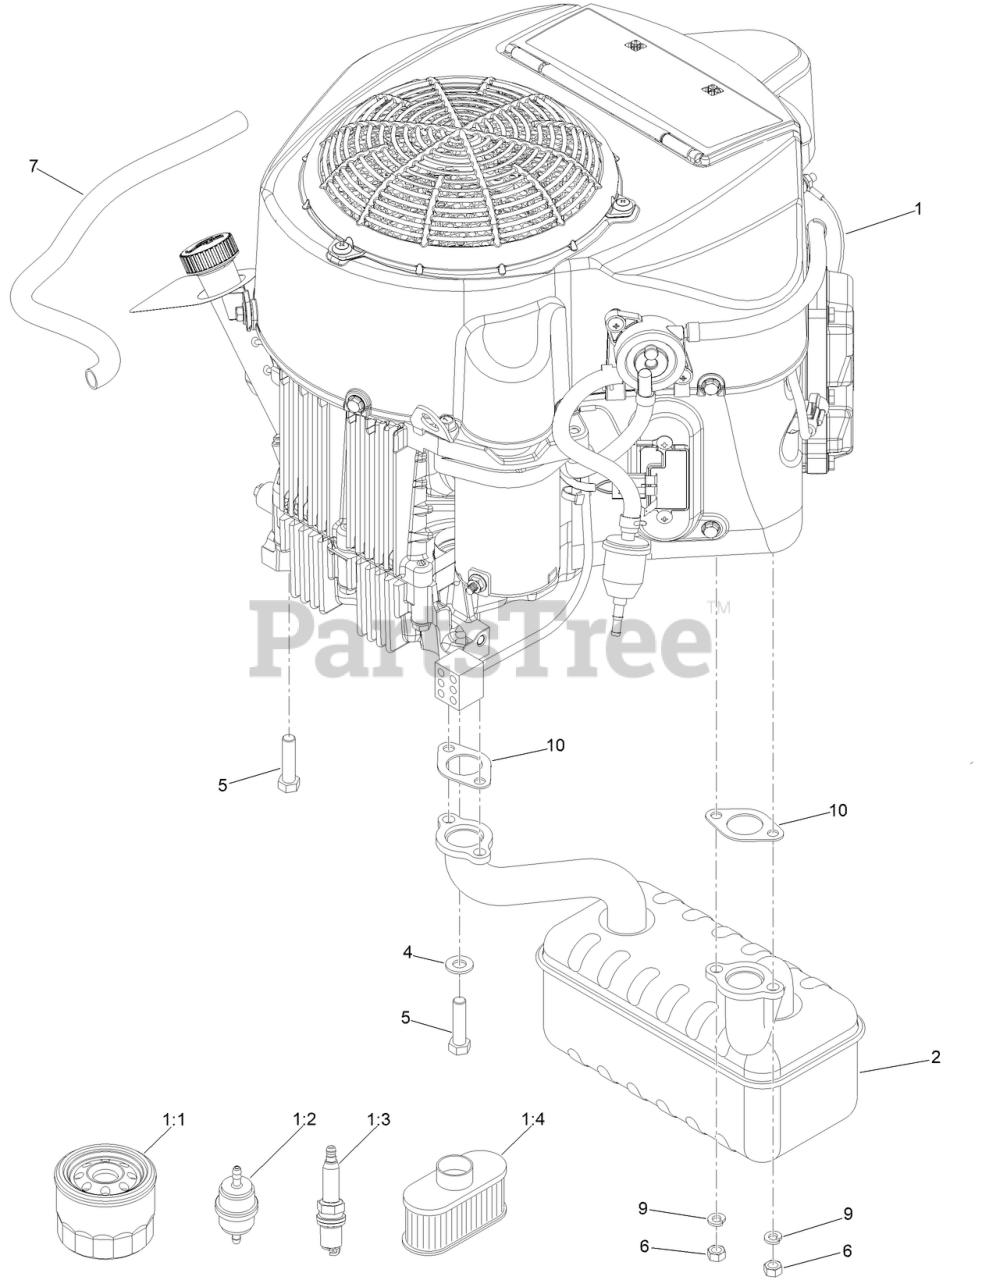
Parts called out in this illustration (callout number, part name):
2	MUFFLER
4	WASHER-FLAT
5	BOLT-HH
7	TUBE-DRAIN, OIL
9	WASHER-LOCK
10	GASKET-EXHAUST
